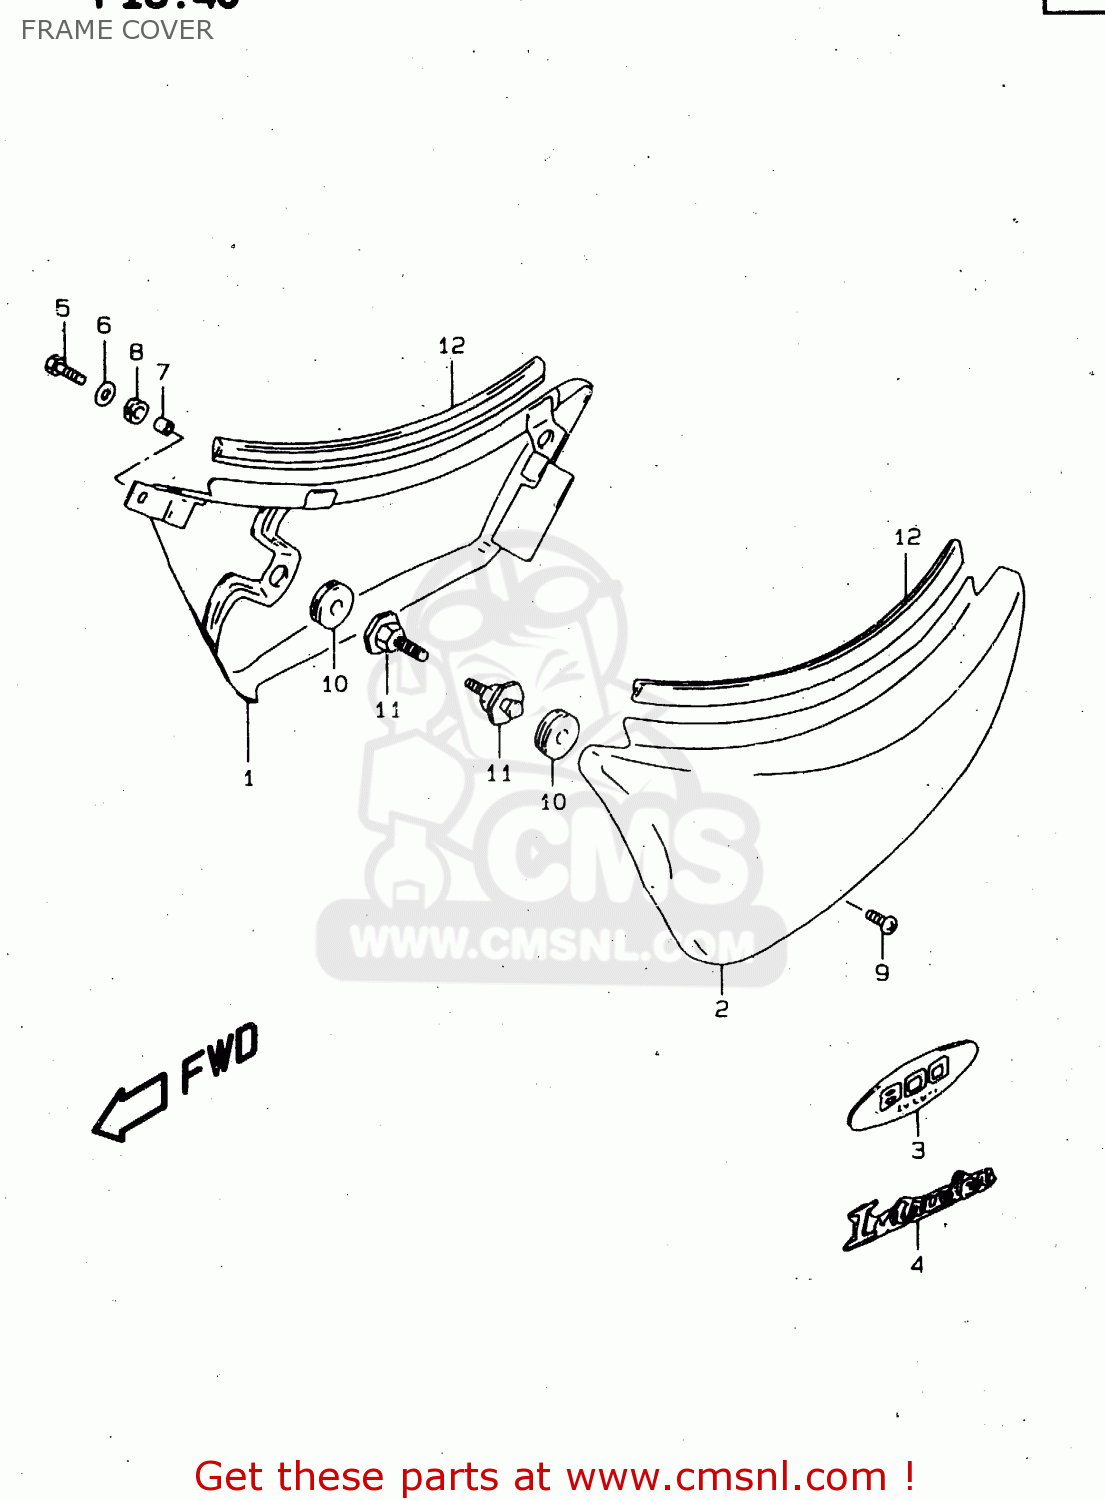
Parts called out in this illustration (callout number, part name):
1	COVER,FRAME,R(RED)
2	COVER,FRAME,L(RED)
3	EMBLEM,FRAME COVER
4	EMBLEM,FRAME COVER
5	BOLT
6	WASHER(6.5X18X1.6)
7	SPACER(6.1X8X5.2)
8	CUSHION
9	SCREW 6X10
10	CUSHION
11	BOSS,FRAME COVER
12	MOLDING
